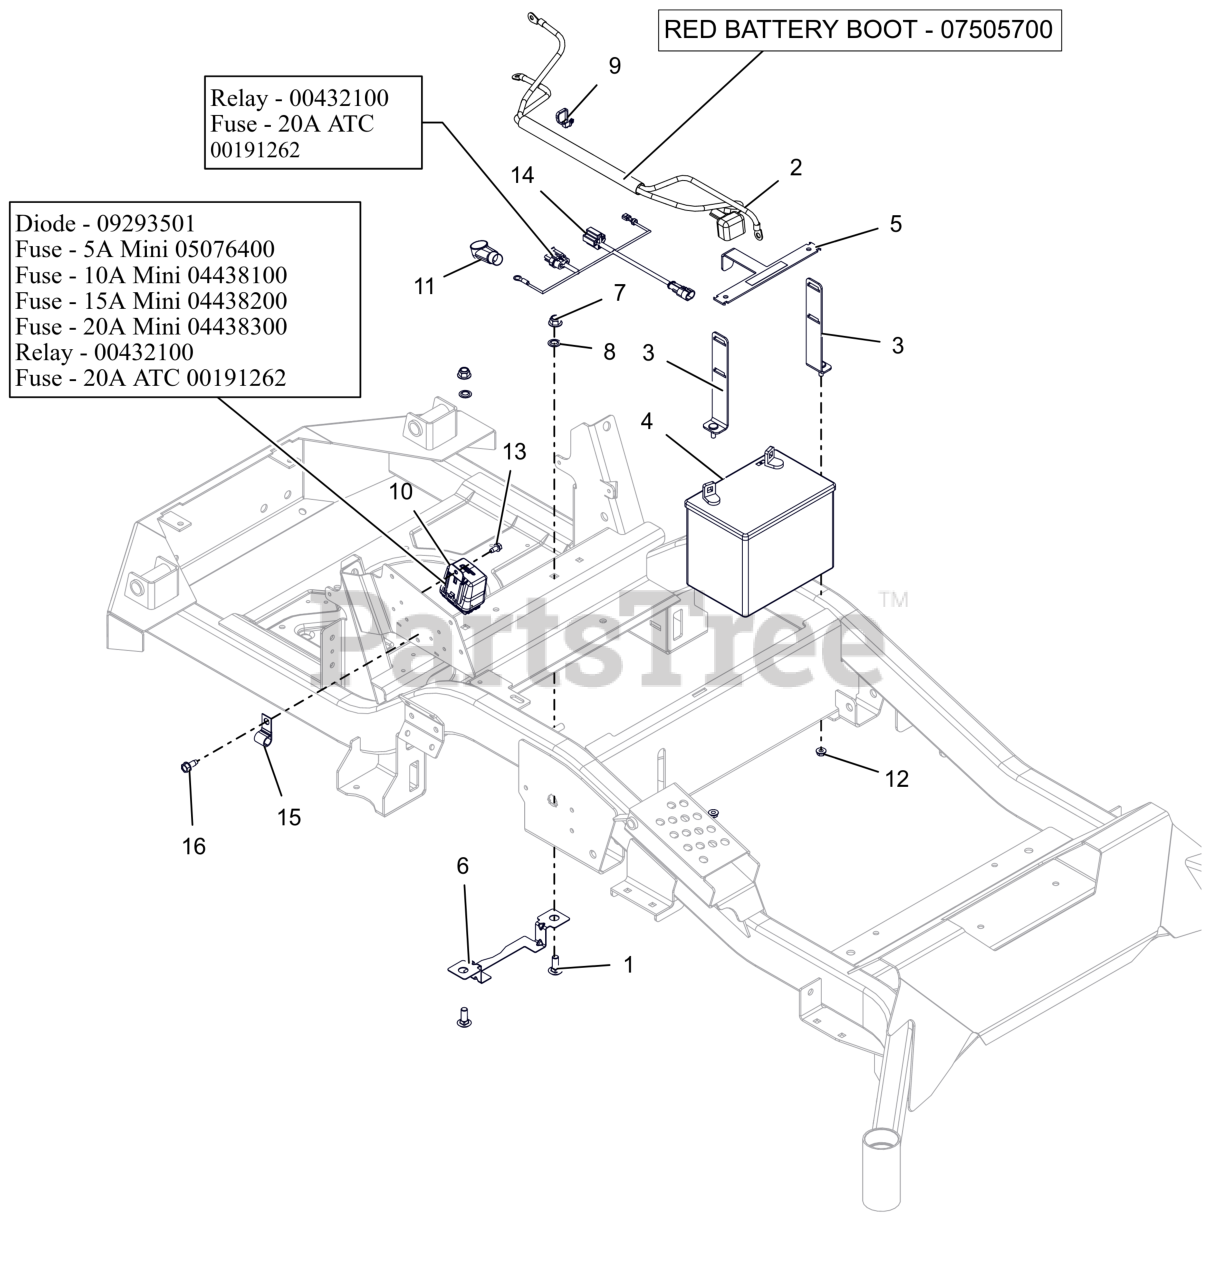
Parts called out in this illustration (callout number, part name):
1	BLT, RHSN .38-16X1.00 G5 ZCC
2	HARNESS, BATTERY HD
2	INSULATOR
3	WMT,BATTERY MOUNT HOLD DOWN
4	BATTERY, 300 CCA 10U1L
5	BRKT, BATTERY TIE DOWN
6	GUARD, ELECTRICAL HARNESS
7	NUT,NYL-FLG .38-16 GF ZCC
8	NUT-PUSH .38 DIA. PAL ZINC
9	CABLE TIE W/ TREE (.25 HOLE)
10	HARNESS, WIRE
10	DIODE, CONNECTOR SHELL
10	FUSE, 5 AMP MINI-ATC
10	FUSE,10 AMP MINI-ATC
10	Fuse, 15 AMP MINI-ATC
10	FUSE,20 AMP MINI ATC
10	RELAY,SEALED W/DIODE
10	FUSE, 20 AMP BLADE S/O
11	BOOT, .65ID POS
12	NUT-LK-TOP-FLG .250-20 GF ZCC
13	SCR-TAP .25-20X.50 HWH ZCC
14	HARNESS, STARTER ADAPTOR
14	RELAY,SEALED W/DIODE
14	FUSE, 20 AMP BLADE S/O
15	J-CLAMP
16	SCR,TAP .312-18X.75 HWH TR ZCC
